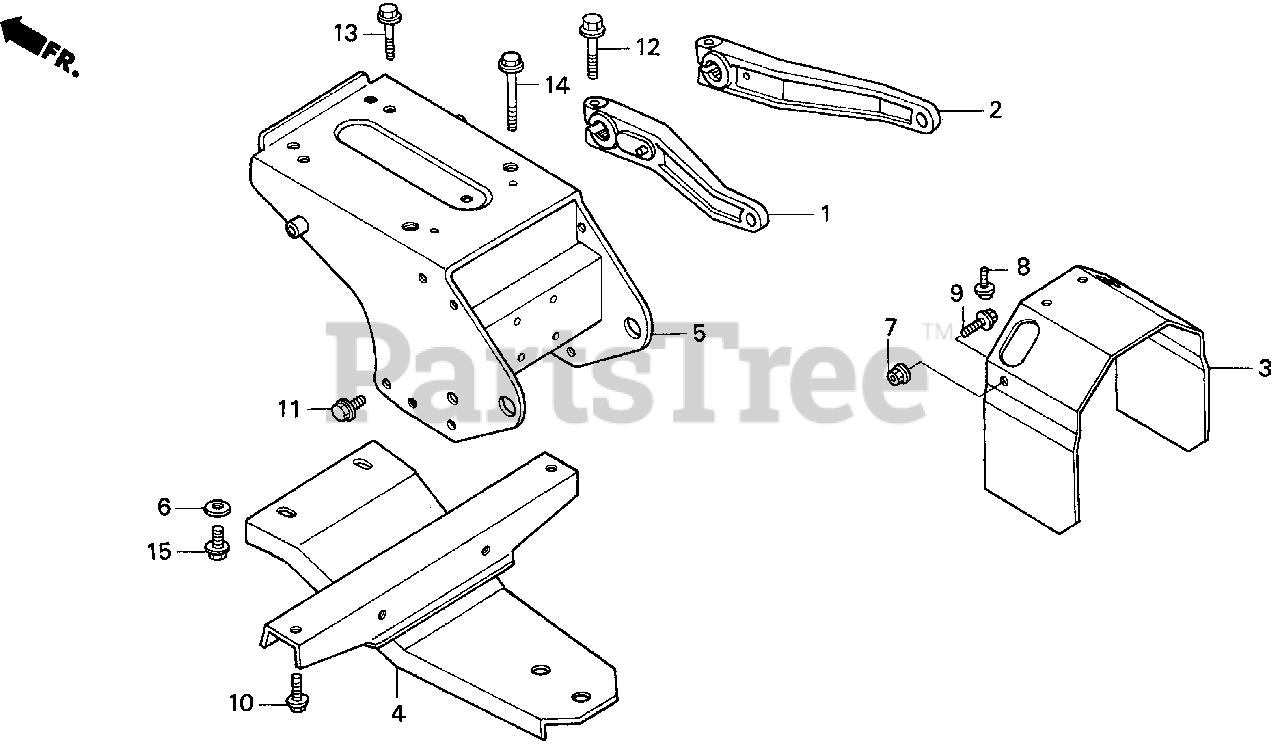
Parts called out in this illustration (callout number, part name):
1	ARM, L. RR. LIFT
2	ARM, R. RR. LIFT
3	SHIELD, RR. P.T.O. MASTER
4	PLATE, DRAWING
5	PLATE, HYDRAULIC CYLINDER MOUNTING
6	WASHER, PLAIN (12MM)
7	NUT, FLANGE (10MM)
8	BOLT, FLANGE (8X14)
9	BOLT, FLANGE (10X20)
10	BOLT, FLANGE (10X22)
11	BOLT, FLANGE (10X25)
12	BOLT, FLANGE (10X40)
13	BOLT, FLANGE (10X50)
14	BOLT, FLANGE (10X70)
15	BOLT, FLANGE (12X30)
